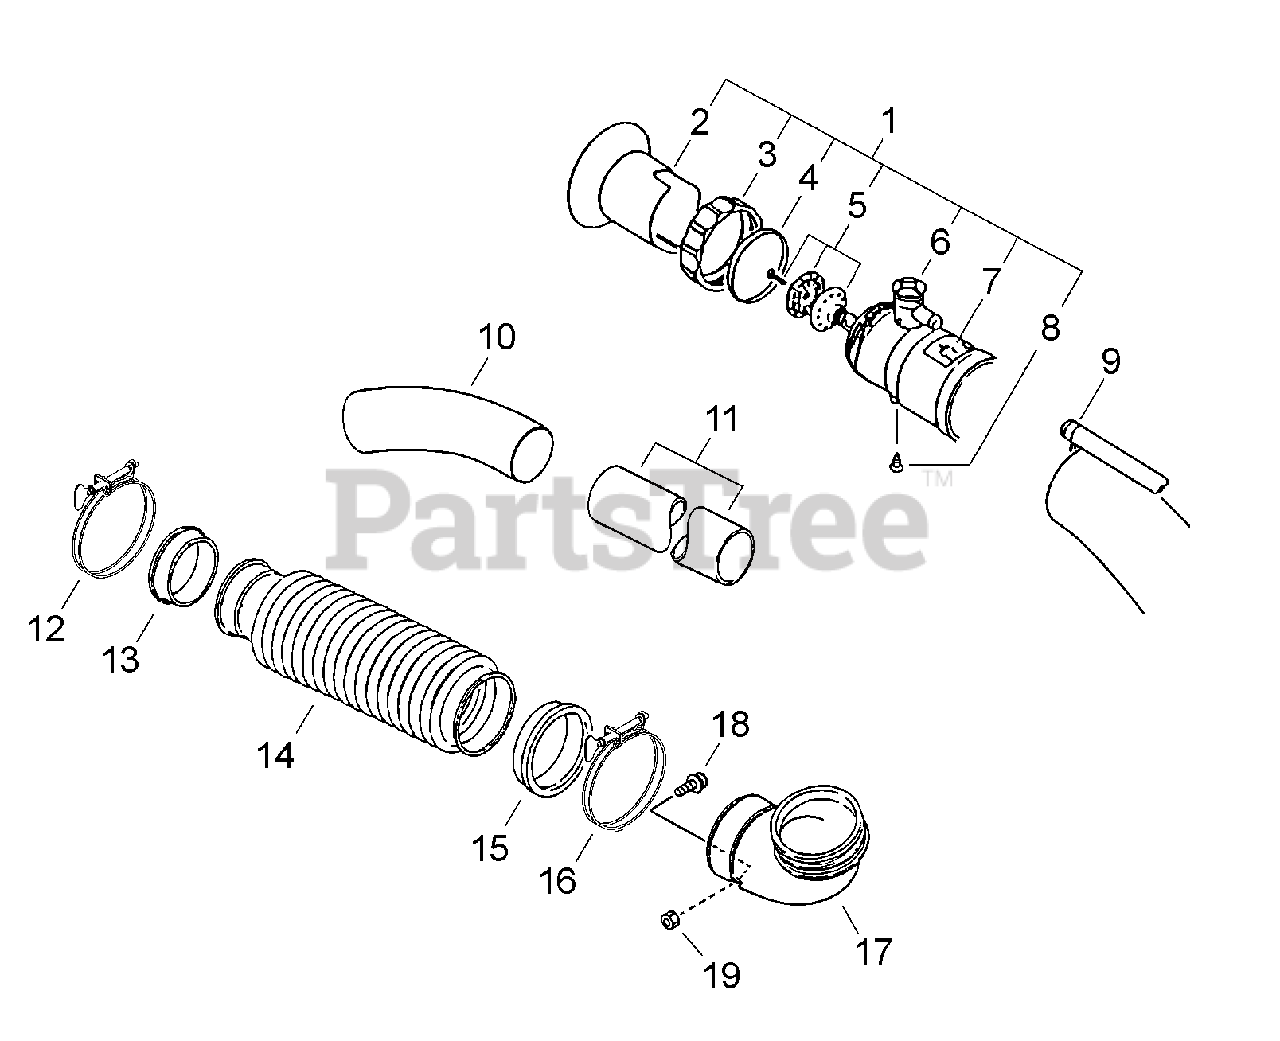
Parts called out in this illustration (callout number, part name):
1	NOZZLE ASSY, MISTING
2	COLLAR, NOZZLE
4	RING, NOZZLE
5	NOZZLE ASSY
6	ADJUSTER, VOLUME
7	LABEL, MIST
8	SCREW 5×12
10	TUBE, BLOWER - CURVED
11	TUBE, BLOWER - STRAIGHT
12	CLAMP
14	TUBE, FLEXIBLE
16	CLAMP
17	TUBE, BLOWER - ELBOW
18	SCREW 5×14
19	NUT M5
